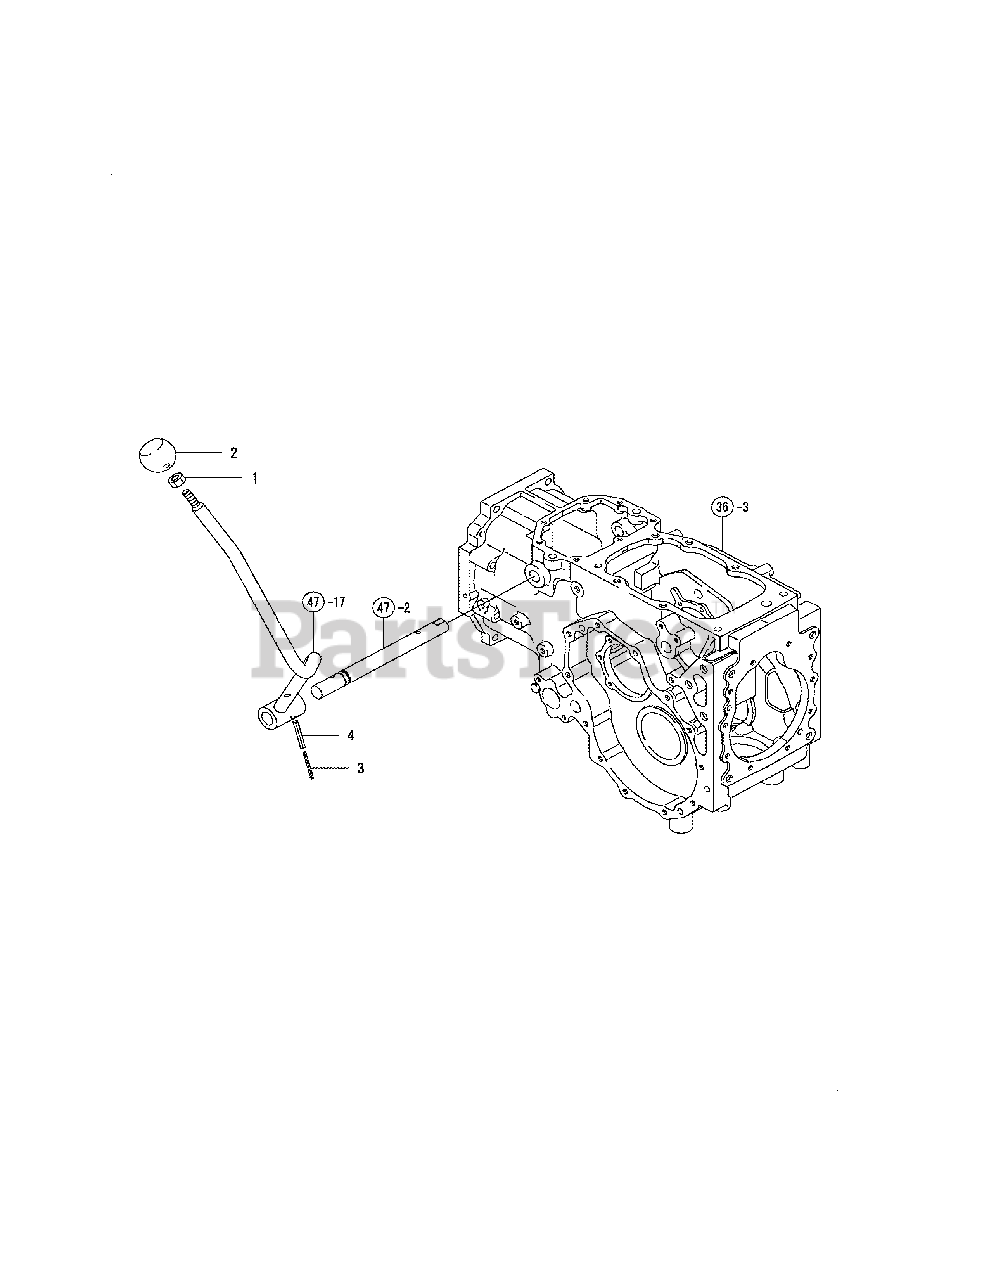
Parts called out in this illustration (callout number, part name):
1	NUT W/WASHER 10
3	SPRING PIN 3.5X40
4	SPRING PIN 6X40
